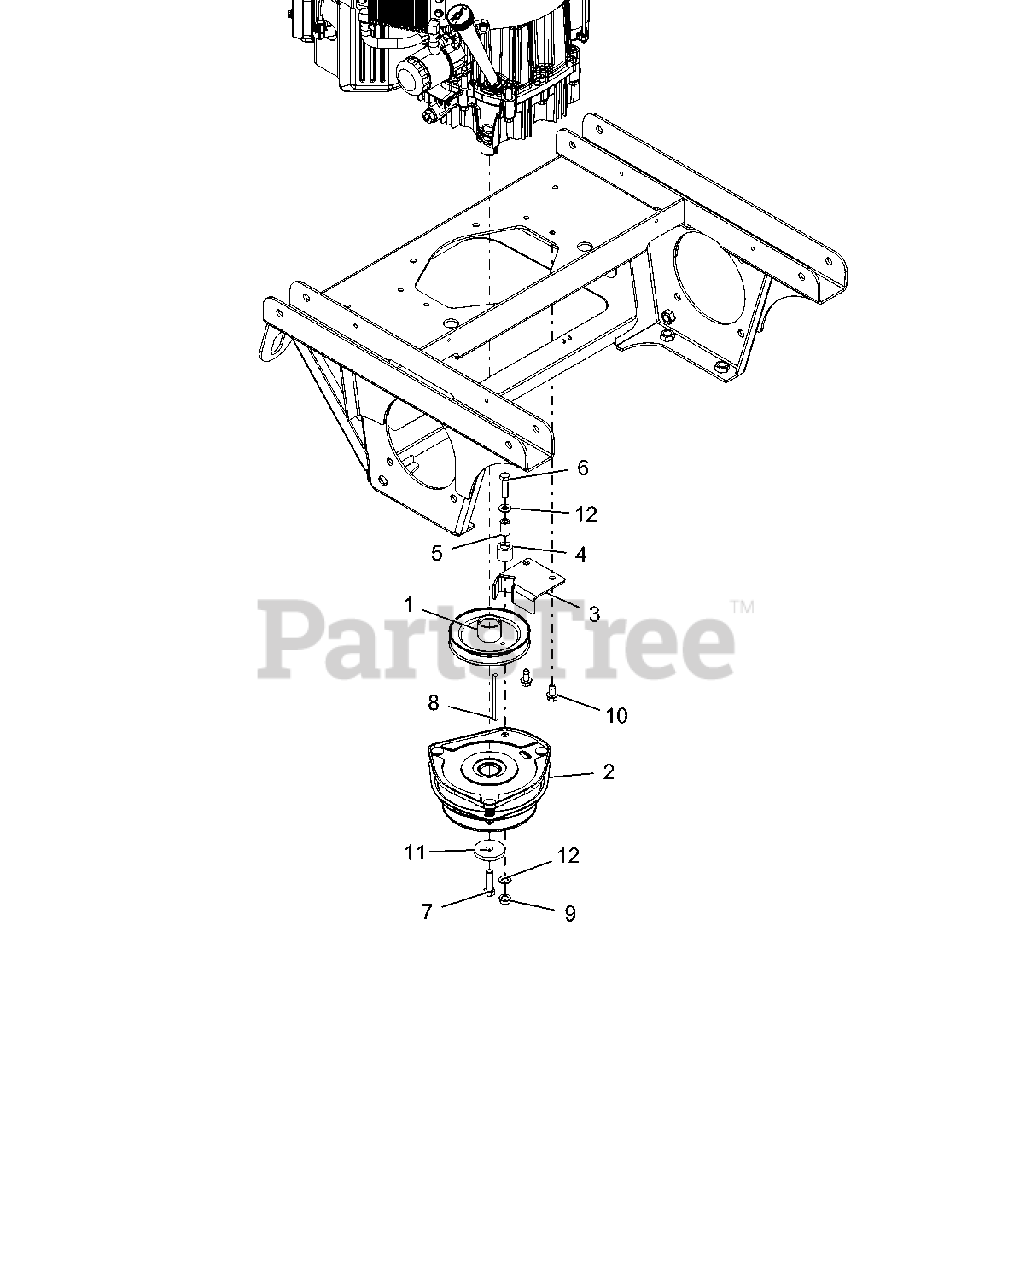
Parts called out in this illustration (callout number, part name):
1	SHEAVE, ENGINE 1.127 ID X 5.250 OD-BLACK
2	CLUTCH-OGURA
3	WLDMT, CLUTCH STOP (BLACK)
4	BUMPER, RUBBER .62 X 1.0 X .88 LG
5	BUSH.,S.391X.622X.95 ST REV A
6	BLT-HEX .38-16X1.50 GR5 YWZC
7	BLT-HEX .44-20X1.50 GR5 YWZC
8	KEY-SQ .250X.250X3.50
9	NUT, LK-TOP-FLG .38-16 YWZC
10	SCR-TAP .38-16X.75 HWH TR YWZ
11	WSHR-FL-STL .469X2.00X.25 YWZC
12	WSHR-FL-STL.406X.812X.065 YWZ
